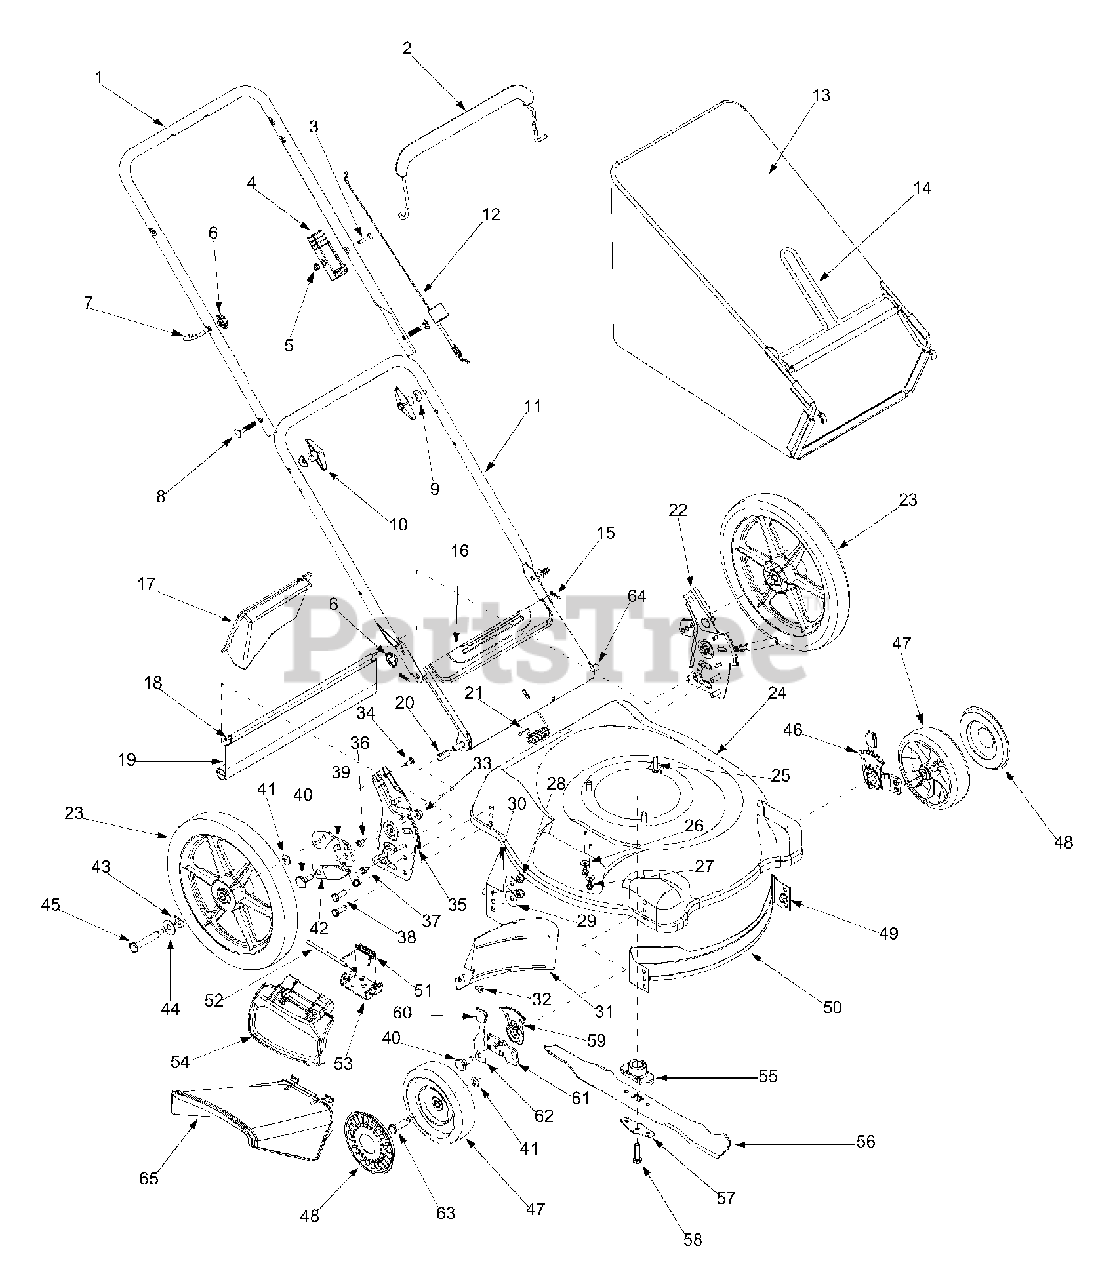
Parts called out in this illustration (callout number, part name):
2	Control Handle Cover
3	C-Sunk Screw 1/4-20 x 1.3"
4	Throttle Housing
5	Hex Lock Nut 1/4-20
6	Handle Knob
7	Rope Guide
8	Carriage Bolt 5/16-18 x 2"
9	Shoulder Washer .320 ID x .930 OD
10	Wing Nut
12	Control Cable 40"
12	Control Cable 37"
12	Control Cable 48"
13	Grass Bag
15	Hairpin Clip
18	Wire Rod
19	Trailshield
20	Spacer .375 O.D. x .50 I.D. x 1.02"
21	Door Spring
22	Handle Bracket Assembly Comp. - RH
22	Handle Bracket Assembly Comp. - LH
23	Rear Wheel Assembly 14 x 2
26	Bell Washer .265 ID x .75 OD
27	Hex Washer Screw 1/4-20 x .500
28	Hex Lock Nut 3/8-16
29	Bell Washer .390 ID x .380 OD
32	Tap Screw 1/4-14 x .625.
33	Flange Lock Nut 3/8-16
34	Hex Carriage Screw 1/4-20
36	Machine Screw 1/4-20 x .500
37	Hex Washer Screw 1/4-14 x .625
38	Hex Cap Screw 3/8-16 x 1.0
39	Pivot Bar - RH
39	Pivot Bar - LH
40	Shoulder Screw
41	Spring Washer .375 ID x .870 OD
42	Spring Lever
43	Wave Washer .500 ID x 1.0 OD
44	Flat Washer .510 ID x 1.37 OD
45	Shoulder Screw
46	Front Height Adjuster - RH
46	Front Height Adjuster - LH
47	Front Wheel Assembly 7 x 2
48	Hubcap
49	Flange Lock Nut 3/8-16
52	Hinge Pin
54	Mulching Plug
55	Blade Adapter
56	21" Mulching
56	21" Standard
57	Blade Bell Support
58	Hex Cap Screw 3/8-24 x 1.5
59	Height Adjustment Plate
60	Height Adjustment Knob
62	Spring Lever
63	Shoulder Bolt
64	Chute Door Pivot Rod
65	Side Discharge Deflector
